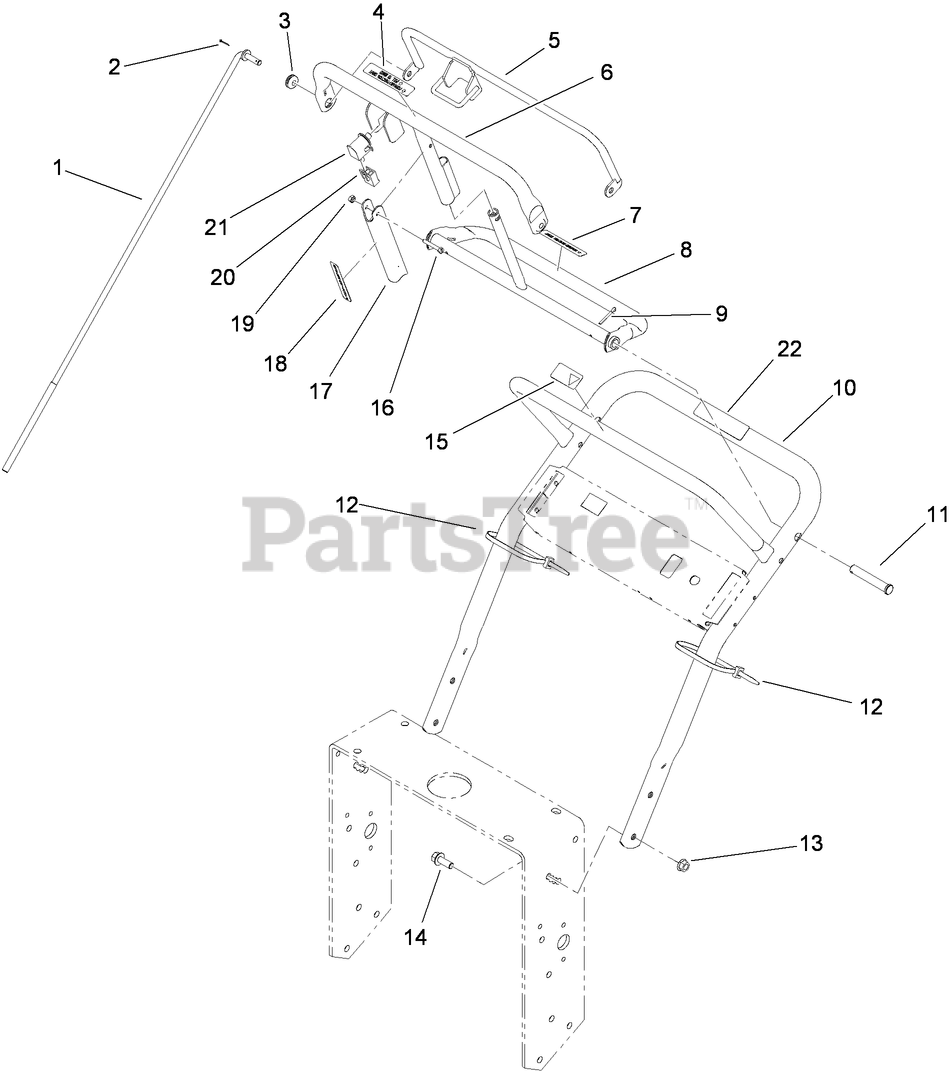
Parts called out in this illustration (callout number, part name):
1	ROD-CONTROL
2	PIN-COTTER
3	GROMMET-RUBBER
4	DECAL
6	BAR-CONTROL
7	DECAL
8	PIVOT-CONTROL
9	PIN-COTTER
10	HANDLE-UPPER
11	PIN-CLEVIS
12	TIE-CABLE
13	NUT-HF
14	SCREW-HHF
15	DECAL-PROTECTION, EAR
16	SCREW-SHH
17	LEVER-BRAKE, PARKING
18	DECAL-LEVER, PARKING
19	NUT-LOCK, NI
20	CONNECTOR-BODY
21	SWITCH-BAIL
22	DECAL-ARRESTER, SPARK
